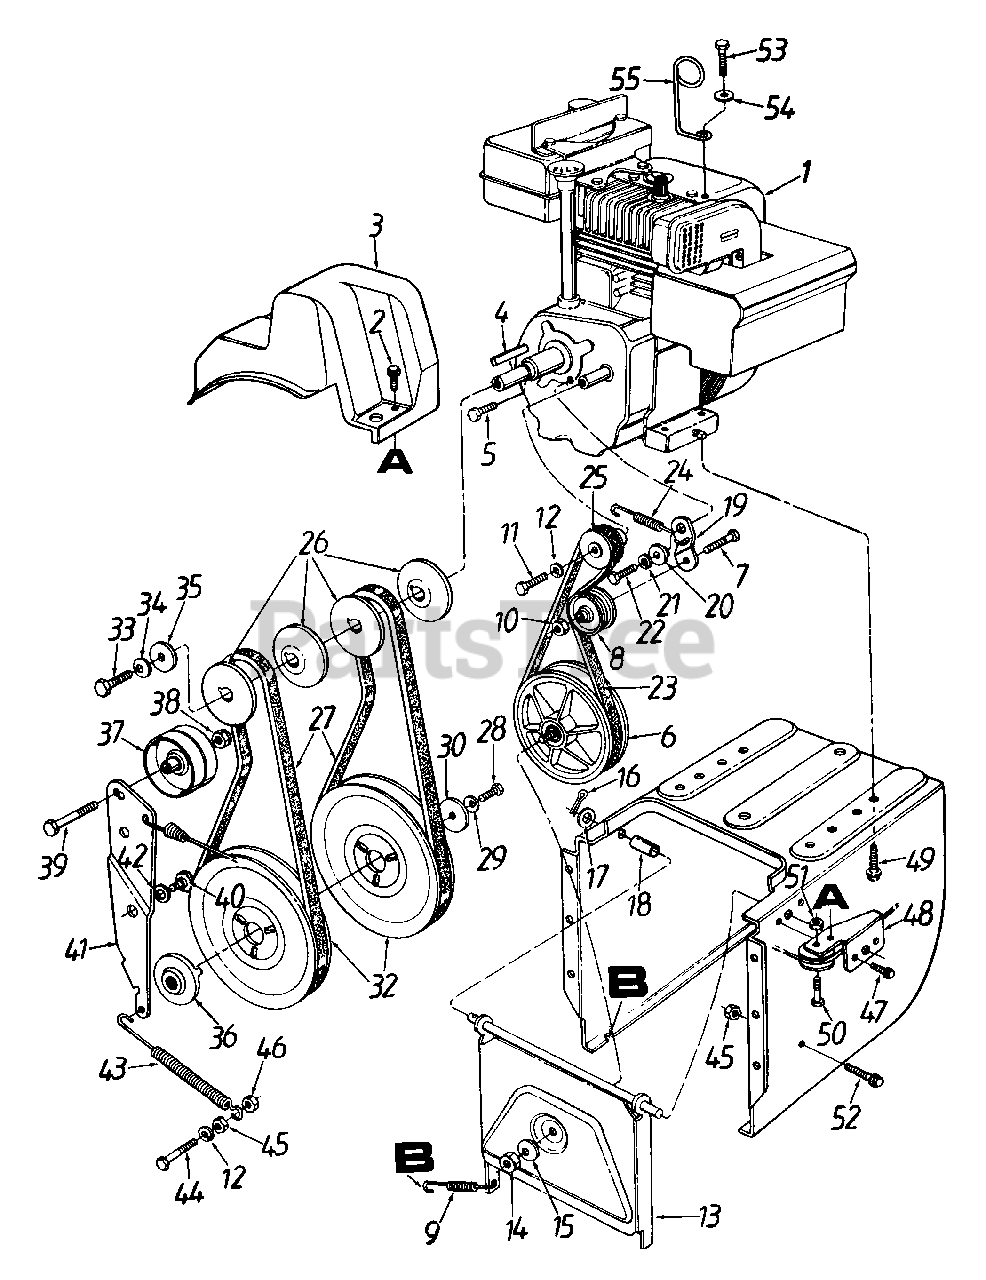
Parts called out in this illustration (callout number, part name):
1	Engine
2	Hex Wash. Hd. TT-Tap Scr. 1/4-20 x .5" Lg.
3	Belt Cover
4	Sq. - Key 3/16 x 1.5" Lg.
5	Hex Patch Bolt 5/16-24 x 1" Lg. (Gr. 5)
6	Friction Wheel Disc Ass'y.
7	Hex Bolt 3/8-16 x 1.25" Lg.
8	Fl-Idler 2.12" O.D.
9	Ext. Spring 2.5" Lg.
10	Hex Top L-Nut 3/8-16 Thd.
11	Hex Bolt 1/4-28 x .5" Lg.
12	L-Wash. 1/4" I.D.
13	Friction Wheel Support Brkt. Ass'y.
14	Hex Jam Nut 3/8-24 Thd.
15	Bell-Wash. .38" I.D. x .88" O.D.
16	Cotter Pin 1/8" x .75" Lg.
17	Fl-Wash. .531" I.D. x .93" O.D.
18	Spacer .508" I.D. x .75" O.D.
19	Drive Clutch Idler Bracket
20	Shld, Spacer .5" Dia. x .27" Lg.
22	Hex Wash. Hd. Tap Scr. 5/16-18 x .62" Lg.
23	V - Belt
24	Extension Spring
25	2" Dia. Pulley
26	3/8 "V" - Pulley Half
27	V - Belt (2)
28	Hex Cap L-Bolt 5/16-24 x .75" Lg.
29	Bell-Wash. .345" I.D. x .88" O.D.
30	Fl-Wash. .34" I.D. x 1.5" O.D.
32	Auger Pulley
33	Hex Bolt 3/8-24 x .88" Lg.
34	Bell-Wash. .39" I.D. x 1.13" O.D.
35	Fl-Wash. .406" I.D. x 1.25" O.D.
36	Adapter Pulley
37	Fl-Idler 2.75" O.D.
38	Hex Ins. L-Nut 3/8-24 Thd.
39	Hex Bolt 3/8-24 x 1.5" Lg. (Gr. 5)
40	Shld. Bolt .625" Dia. x .170" Lg.
41	Auger Idler Brkt.
42	Wave Wash. .66" I.D. x .88"
43	Ext. Spring 3.6" Lg.
44	Hex Bolt 1/4-20 x .75" Lg. (Gr. 5)
45	Hex Nut 1/4-20 Thd.
46	Hex L-Nut 1/4-20 Thd.
47	Torx Mach. AB-Tap Scr. 1/4 x .62" Lg.
48	Front Support Brkt. Guide
49	Hex L-Wash. TT-Tap Scr. 3/8-16 x 1.25" Lg.
50	Shld. Bolt 5/16" Dia. x .35" Lg.
51	Hex Jam Nut 1/4-20 Thd.
52	Hex Wash. Hd. TT-Tap Scr. 1/4-20 x 1" Lg.
53	Hex Wash. Hd. Tap Scr. 5/16-18 x 1" Lg.
54	Fl-Wash, .349" I.D. x .879" O.D.
55	Cable Control Wire
